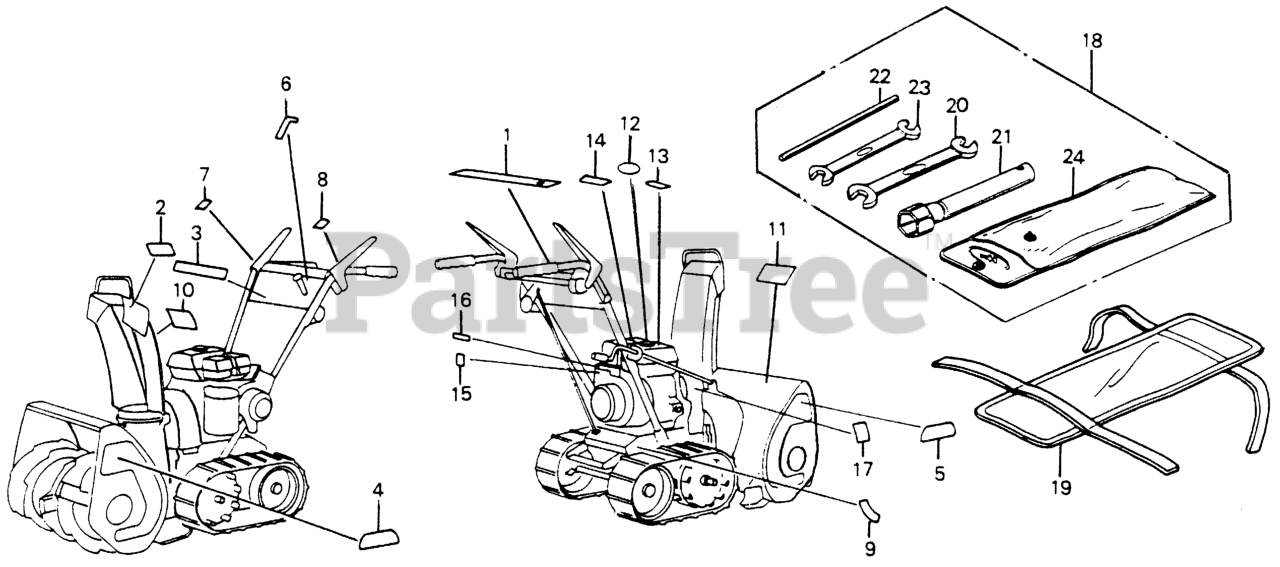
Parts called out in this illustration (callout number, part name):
1	MARK, CONTROL PANEL
2	LABEL, WARNING (ENGLISH)
3	EMBLEM, CONTROL PANEL
4	EMBLEM, L. SIDE COVER (22")
5	EMBLEM, R. SIDE COVER (22")
6	MARK, CHANGE
7	MARK, AUGER CLUTCH
8	MARK, CLUTCH
8	MARK, CLUTCH (NOT AVAILABLE)
9	MARK, HEIGHT ADJUSTING
10	MARK, HOUSING DANGER (ENGLISH)
11	MARK, DISCHARGE DANGER (ENGLISH)
12	MARK, CAUTION (EXTERNAL)
14	MARK, FUEL CAUTION
15	MARK, CHOKE
16	MARK, THROTTLE
17	MARK, OIL CAUTION
19	BAG, TOOL
20	SPANNER (12X14)
21	WRENCH, SPARK PLUG (NOT AVAILABLE)
22	HANDLE, BOX WRENCH (NOT AVAILABLE)
23	WRENCH (10X14) (OPEN END)
24	BAG, TOOL
